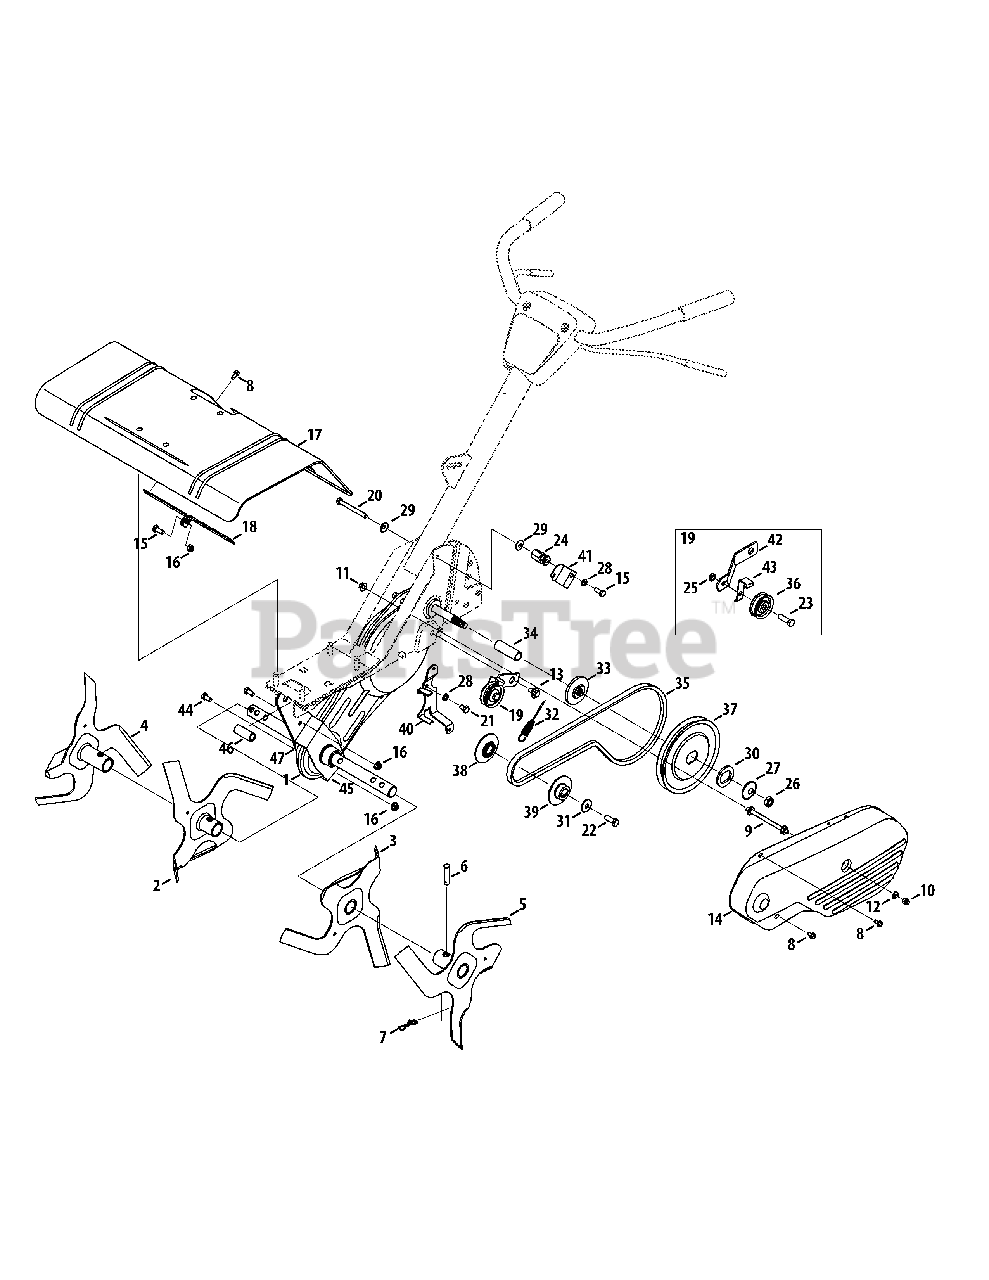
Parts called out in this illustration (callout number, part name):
1	Chain Case Assembly
2	Inner Tine Assembly, RH
3	Inner Tine Assembly, LH
4	Outer Tine Assembly, RH
5	Outer Tine Assembly, LH
6	Clevis Pin, 375 x 175
7	Bow Tie Cotter Pin
8	Screw, 1/4-20 x 0500
9	Bolt, Belt Cover
10	Nut, 1/4-28, Lock
11	Nut, 5/16-18, Flange Lock
12	Flat Washer, 271 x 630 x 065
13	Shoulder Screw, 560 x 165 5/16-18
15	Hex Head Screw, 5/16-18 x 75
16	Nut, 5/16-18, Flange Lock
18	Bracket, Tine Shield
19	Idler Bracket Assembly
20	Hex Head Screw, 5/16-18 x 300
21	Hex Head Screw, 5/16-24 x 625
22	Hex Head Screw, 3/8-24 x 100
23	Hex Head Screw, 3/8-16 x 125
24	Hex Nut, 5/16-18
25	Jamlock Nut, 3/8-16
26	Nut, 1/2-20, Jam
27	Washer, 531 x 162 x 045
28	Lock Washer, 5/16
29	Bell Washer, 340 x 872 x 060
30	Flat Washer, 126 x 187 x 150
31	Bell Washer, 396 x 1140 x 095
32	Forward Clutch Cable
33	Pulley Adaptor
34	Spacer, 64 ID x 24
35	Belt, 4L x 419 LG
36	Pulley 188 OD
37	Pulley 600 OD
38	Inner Engine Pulley
39	Outer Engine Pulley
40	Belt Keeper Bracket
41	Cable Guide Bracket
42	Idler Bracket
43	Belt Keeper
44	Hex Head Screw, 5/16-18 x 625
45	Bracket, Chain Case, LH
46	Spacer, 505 ID x 75 OD x 175
47	Bracket, Chain Case, RH
